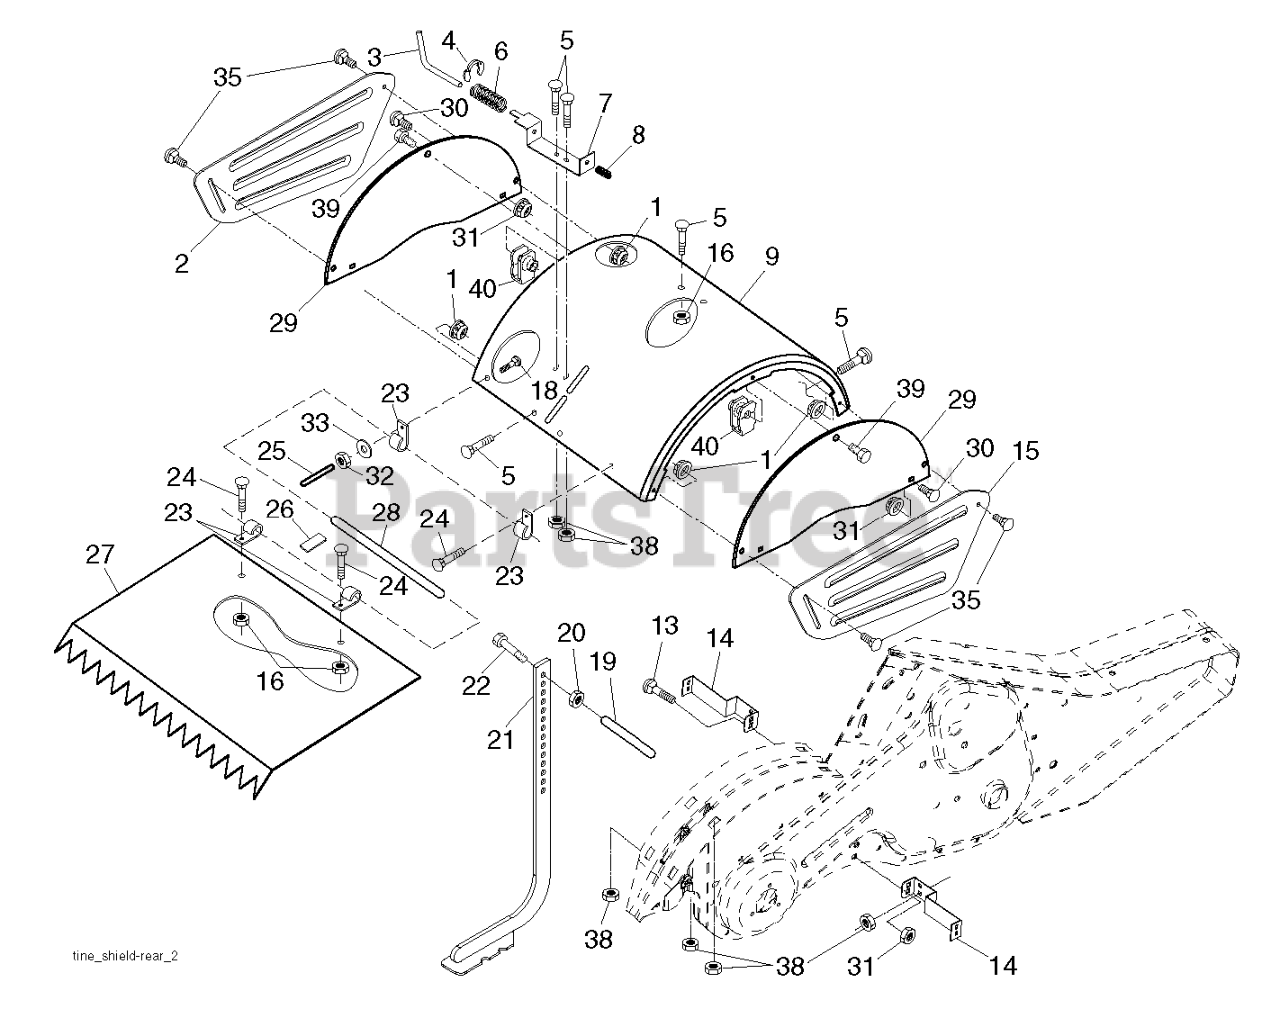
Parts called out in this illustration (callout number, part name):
1	NUT.FLANGE.5/16
2	SHIELD.PNT.SIDE.OUTER.LH.ORANG
3	STAKE PIN TI
4	RING, KLIP
5	BOLT, RDHD SQNK 5/16-18 X 3/4
7	BRACKET
8	SPRING CRT
9	SHIELD.TINE.TILLER.ORANGE
13	BOLT.CARRIAGE.5/16-18
14	BRACKET.TINE.SHIELD.TILLER.BLA
15	SHIELD.SIDE OUTER.RH.ORANGE
16	NUT T
20	NUT.HEX.3/8-16UNC
21	REPL BY 532 10 21-56
22	BOLT.375-16
24	BOLT
25	VINYL CAP TI
26	PAD IDLER TI
27	SHIELD.LEVELING.17".ORANGE
28	PIN.HINGE.TILLER
29	SHIELD.TINE.SIDE.ORANGE
30	BOLT.CARRIAGE.5/16-18X
31	LOCKNUT-FLANGE 5/16-18
32	NUT
33	LOCKWASHER
35	BOLT.CARR.5/16-18X5/8.SHORT
38	NUT
39	BOLT.HEX.HD.WASHER.5/16-18X.75
40	NUT.SPEED.5/16-18
